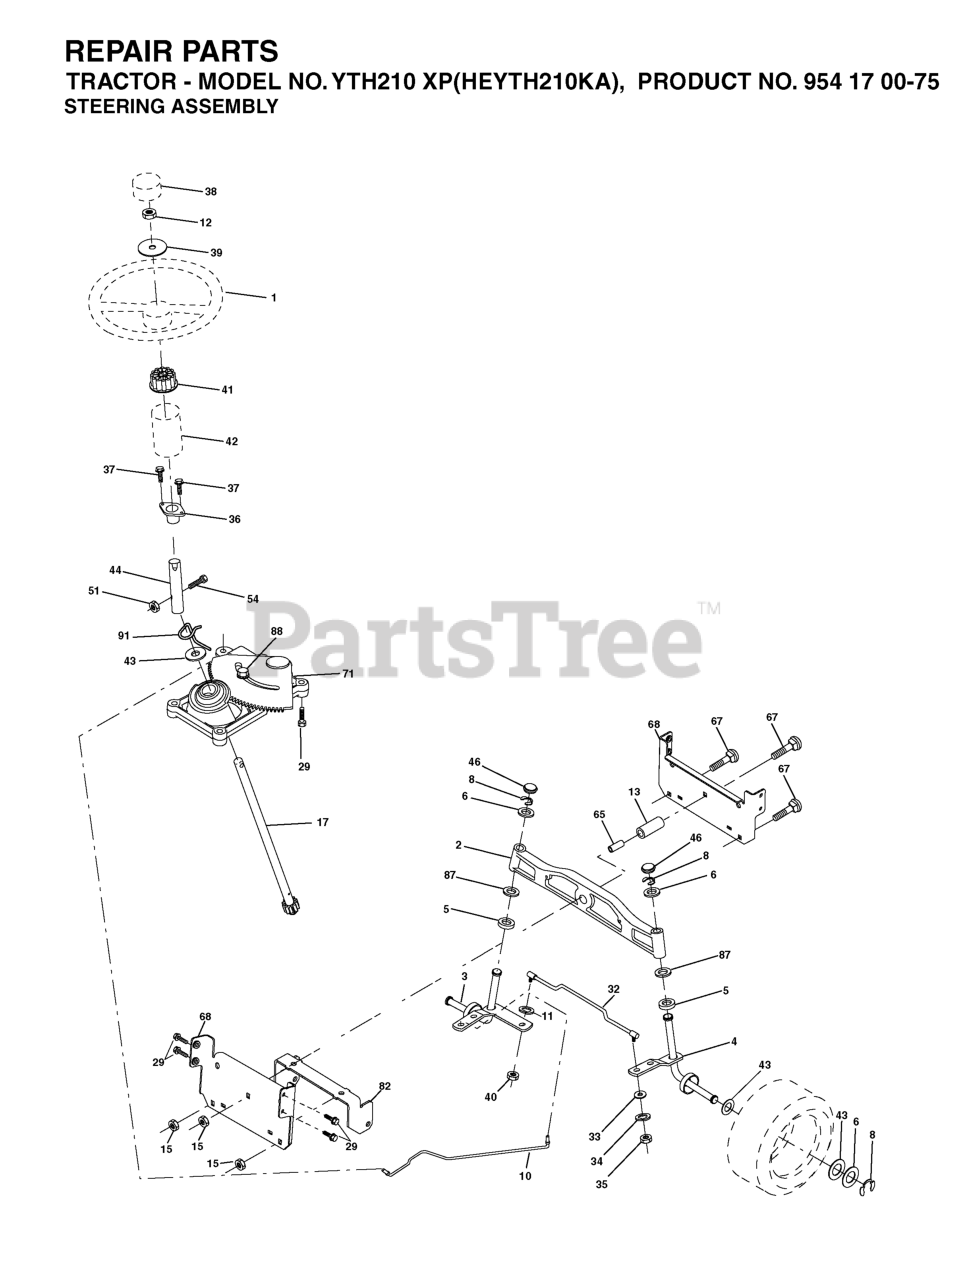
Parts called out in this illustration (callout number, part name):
1	STEERING WHEEL
2	AXLE ASM
3	SPINDLE.ASM.LH.15"TIRES
4	SPINDLE.ASM.RH.15"TIRES
5	THRUST WASHER
10	DRAGLINK.15".TIRES.2001
11	WASHER, LOCK 3/8
12	NUT.HEX.1/2-20
13	TUBE, PIVOT AXLE
15	NUT
17	SHAFT ASM, STEERING
29	SCREW 3/8-16X3/4
33	WASHER M
34	WASHER.LOCK.HVY.HLCL.SPR.5/16
35	NUT, CROWNLOCK
36	BUSHING, STEERING
37	SCREW.TT.#10-32X.5.3/8.FLANGE
38	CAP.WHEEL.STEERING.GREY
39	Washer 9/16 ID x 1 1/2 OD 11 Ga. Zin
40	GRIPCO NUT
41	STEERING WHEEL ADAPTOR
42	BOOT STEERING
44	EXT, STEERING SHAFT
46	CAP.SPINDLE.BLACK
51	NUT.CROWNLOCK.1/4-28
54	Bolt Hex 1/4-28 unf x 1-1/4 Gr. 8
65	SPACER BRACE AXLE
67	BOLT
68	BRACE.AXLE.15"TIRES
71	STEERING ASM
82	BRACKET
87	WASHER, FLAT .781 X 1 1/2"
88	BOLT, SHOULDER 7/16-20
91	CLIP.STEERING
